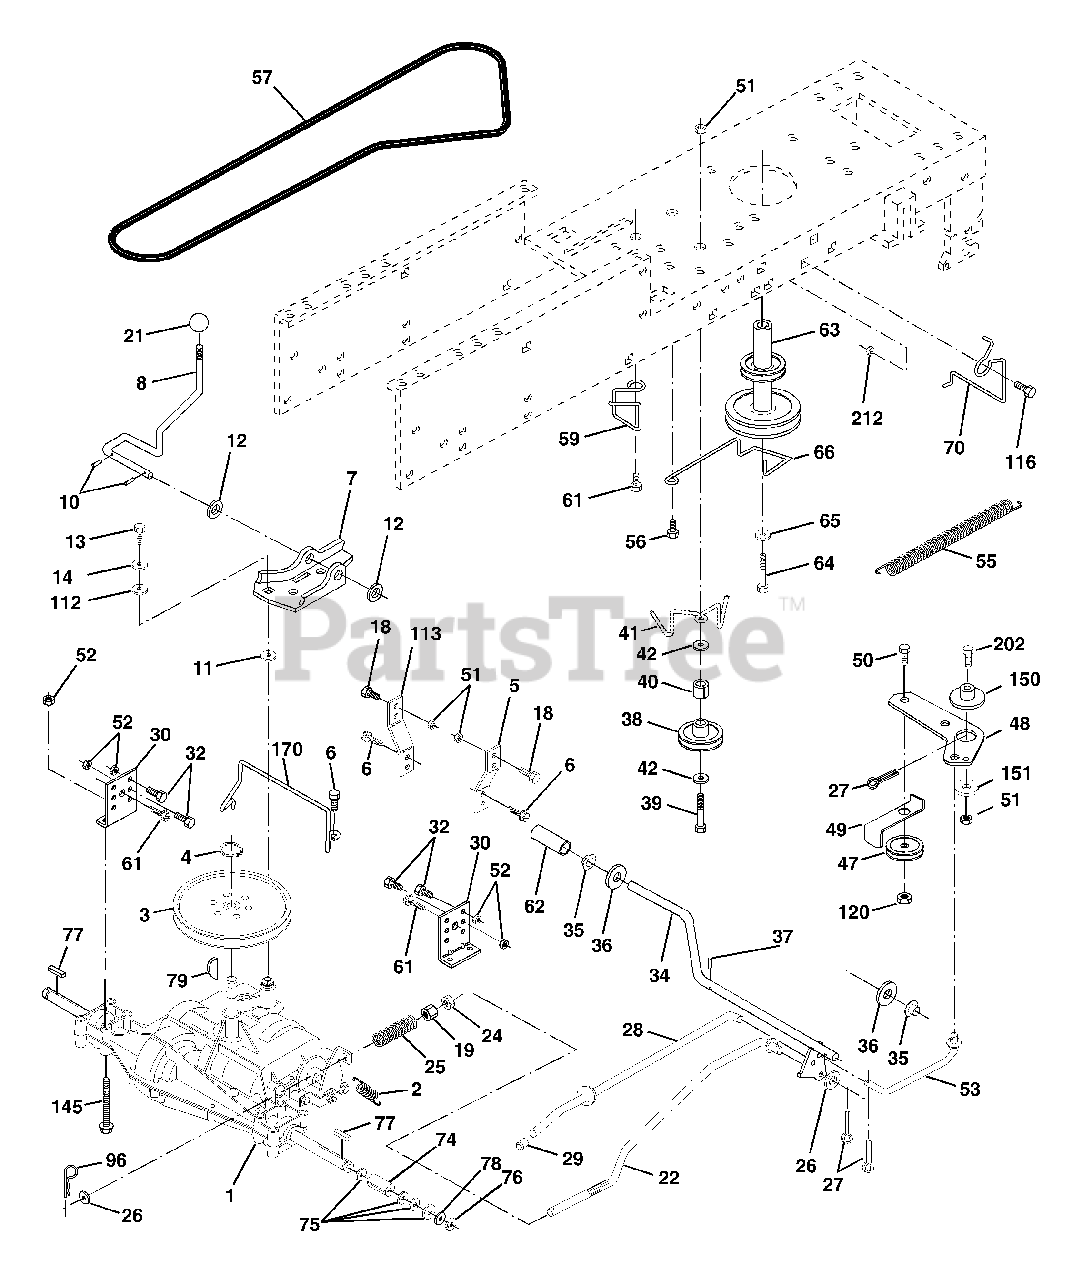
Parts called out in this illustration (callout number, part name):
2	Spring Extension Brake
3	Pulley Transaxle 18" tires
4	Ring Retainer # 5100-62
5	Strap Torque Rh Pnt Blk
6	Screw 5/16-18 X 3/4
7	Bracket T/A Saddle Shift
8	Rod Shifter Black(dana)
10	Pin,Cotter
11	Washer Plate Shf 388 Sq Hole
12	Washer 15/32 X 3/4 X 16ga
13	Bolt 1/4-28 UNF Gr. 8 W/Patch
14	Washer
18	Bolt Fin Hex 3/8-16 UNC x 1 Gr. 5
19	Nut
21	Knob Rd 1/2-13 Plstc Thds Blk
22	Rod Brake Lt
24	Nut
25	Spring Rod Brake 2 00 Zinc
26	Washer
27	Pin
28	Rod Brake Parking
29	Cap Parking Brake
30	Bracket Transmission
32	Bolt
34	Shaft Asm Pedal Foot
35	Bearing Nylon Blk 629 Id
36	Washer
37	Roll Pin
38	Pulley Idler Flat
39	Bolt Fin Hex 3/8-16 Unc x 3
40	Spacer Split
41	Keeper Belt Idler
42	Washer 13/32 X 13/16 X 12 Ga
47	Pulley Idler V Groove Plastic
48	Bellcrank Clutch
49	Retainer Belt Style Spring
50	Bolt
51	Nut
52	Nut
53	Link Clutch 7 66
55	Spring Return Clutch 6 75
56	Screw 3/8-16 x 1.0
57	V-belt Ground Drive 95
59	Keeper Belt Chassis Span Ctr.
61	Screw 3/8-16x3/4
62	Cover Pedal Blk Round
63	Pulley Engine
64	Bolt, Hex 7/16-20 x 4 Grade 5
65	Washer, Lock, Hvy Hlcl Spring 7/16
66	Keeper Belt Engine Flproof
70	Guide Belt Dr Mower Rh
72	Washer 13/32 X 1-1/4 X 12 Ga
74	Spacer Axle
75	Washer 25/32 X 1 1/4 X 16 Ga
76	E Ring
77	Key Square 2 0 X 1845/ 1865
78	Washer 25/32 X 1 5/8 X 16ga
79	Key Woodruff
96	Retainer Spring 1"
112	Washer 9/32 X 3/4 X 10 Ga
113	Strap Torque Lh
116	Bolt, Rdhd Sqnk 3/8-16 x 1.00
120	Nut Lock Flg 3/8-16
145	Bolt Hex Flghd 5/16-18 x Gr. 5
150	Spacer Retainer
151	Washer 13/32 x 2 x 10 Ga.
170	Keeper Belt
202	Bolt Carr. Sh. 3/8-16 x 1-3/4 Gr. 5
204	Screw 5/16-18 x 1
212	Nut Hex Flange Lock
